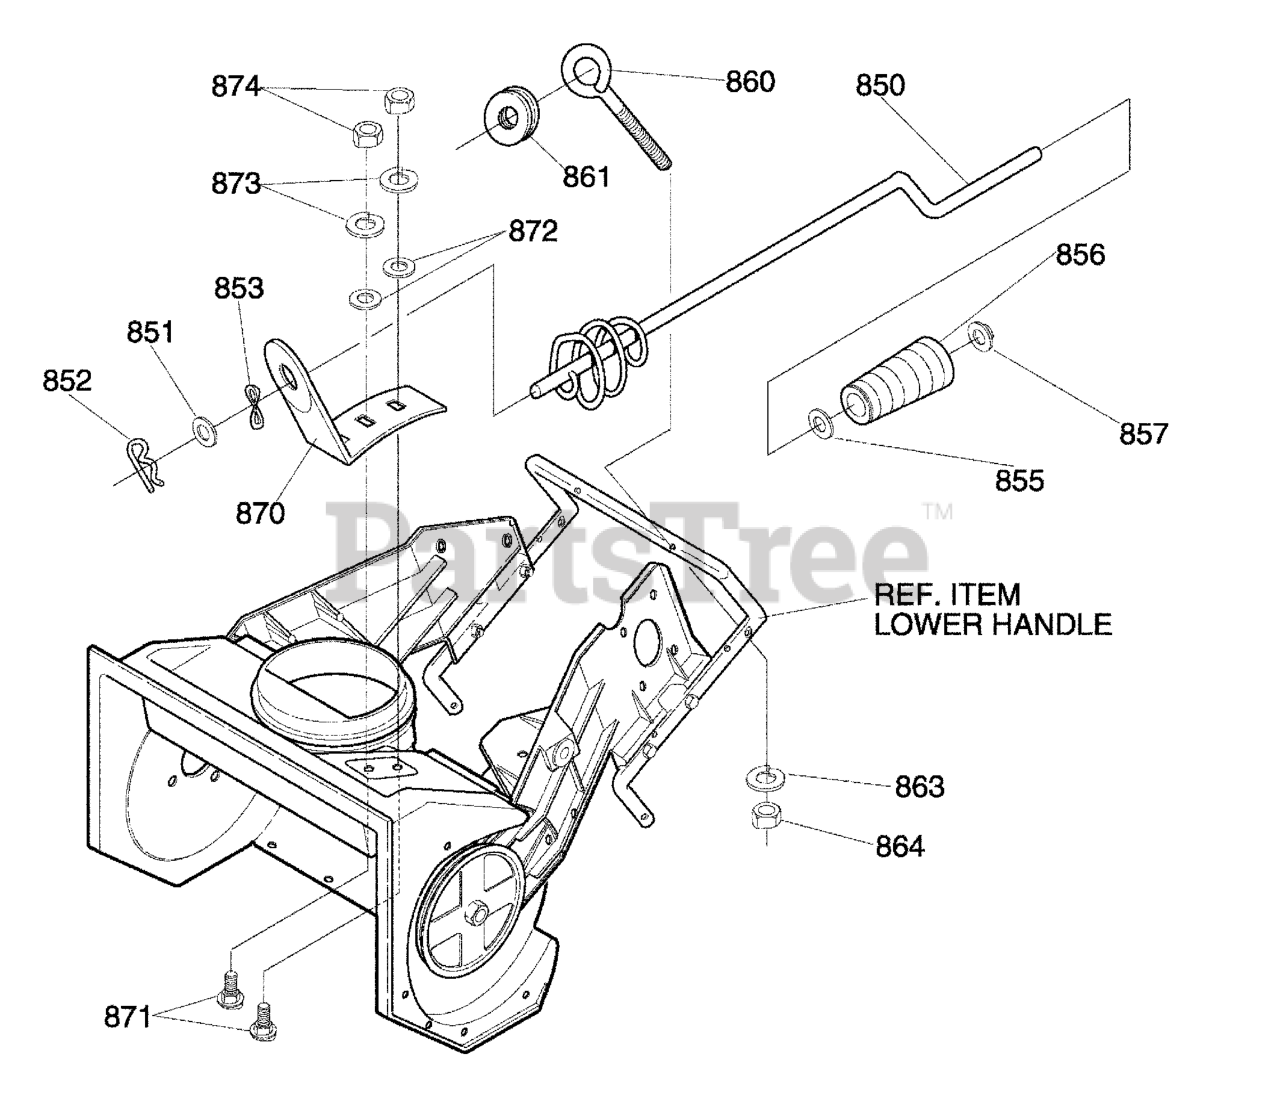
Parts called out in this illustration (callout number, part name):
850	ROD, ASSY UPPER CHUTE CONTROL
851	WASHER, FLAT
852	PIN, COTTER
853	WASHER, CURVED SPRING
855	WASHER, FLAT
856	KNOB, SLEEVE
857	NUT, PUSH
860	BOLT, EYE 3/8-16X2.00
861	GROMMET, EYE BOLT
863	WASHER, MDSPTLK
864	NUT, 3/8-16 HEXJAM
870	BRACKET, CHUTE ROTATE
871	BOLT, CARRIAGE
872	WASHER, FLAT
873	WASHER
874	NUT, 5/16-18
